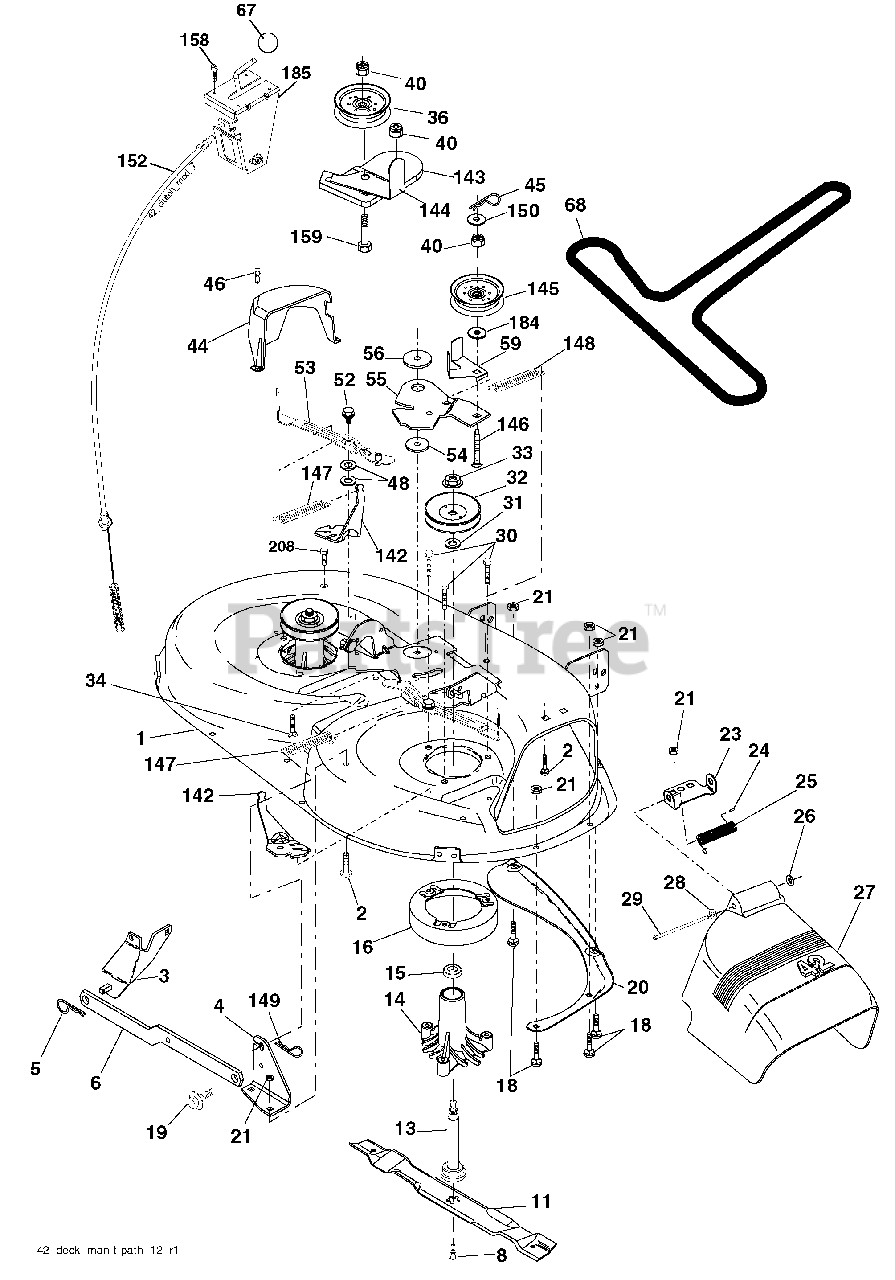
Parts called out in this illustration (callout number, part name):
1	Mower Deck Assembly, 42"
2	Bolt
3	Bracket Asm Fr. Sway Bar 3/42
4	Bracket Asm Deck 42" Sway Bar
5	Retainer Spring
6	Bar Sway Deck
8	Bolt/Washer Asm. 7/16-20 unf (The following Blades are available)
11	Blade Mower 42” Hi-Lift (for bagging and discharging)
11	Blade, Mulching 42” Std (for mulching mowers only)
11	Blade Mulching 42” Premium (For better wear when mulching)
13	Shaft As m. Mandrel
14	Housing Mandrel
15	Bearing, Ball, Mandrel
16	Stripper, Mandrel Deck
18	Bolt, Carriage 5/16-18 x 5/8
19	Bolt, Shoulder
20	Baffle, Vortex
21	Nut
23	Bracket, Deflector Mower 42"
24	Cap, Sleeve 80 x 112 Blk Mower
25	Spring, Torsion, Deflector 2 52
26	Nut, Push Phos & Oil
27	Shield, Deflector 42" Blk
28	Washer 11/32 x 5/8 x 16 Ga.
29	Rod, Hinge 42" 6 75 w/G
30	Screw Thdrol
31	Washer, Spacer Mower Vented
32	Pulley, Mandrel
33	Nut, Toplock
34	Bolt Carr SH 3/8-16 x 1-1/2 Gr.5
36	Pulley, Idler, Flat
40	Nut Lock 3/8-16
44	Guard, Mandrel, LH
45	Retainer
46	Screw, Thdrol 1/4-20 x 5/8 T
48	Washer, Hardened
52	Bolt, Shoulder 5/16-18 unc
53	Arm Assembly, Pad, Brake
54	Washer, Hardened
55	Arm, Idler
56	Spacer, Retainer
59	Guard TUV Idler
67	Knob Round
68	V-Belt, 42" Mower
142	Anchor Spring Brake Mower
143	Bracket Arm Idler 42"
144	Keeper Belt 42" Clutch Cable
145	Pulley Idler Flat
146	Bolt Carriage Idler
147	Spring Extension
148	Spring Return Idler
149	Retainer Spring Yellow
150	Washer 9/32 x 3/4 x 10 Ga.
152	Clutch Cable 42"
158	Screw Hex Thd Cut 1/4-20 x 1/2
159	Bolt Rdhd Sqn 3/8-16 unc x 1-3/4
184	Washer 13/32 x 7/8 x 10 Ga.
185	Head Asm Cable Clutch
208	Screw Thdrol 3/8-16 x 1/2
208	Mandrel Assembly
208	Replacement Mower, Complete
